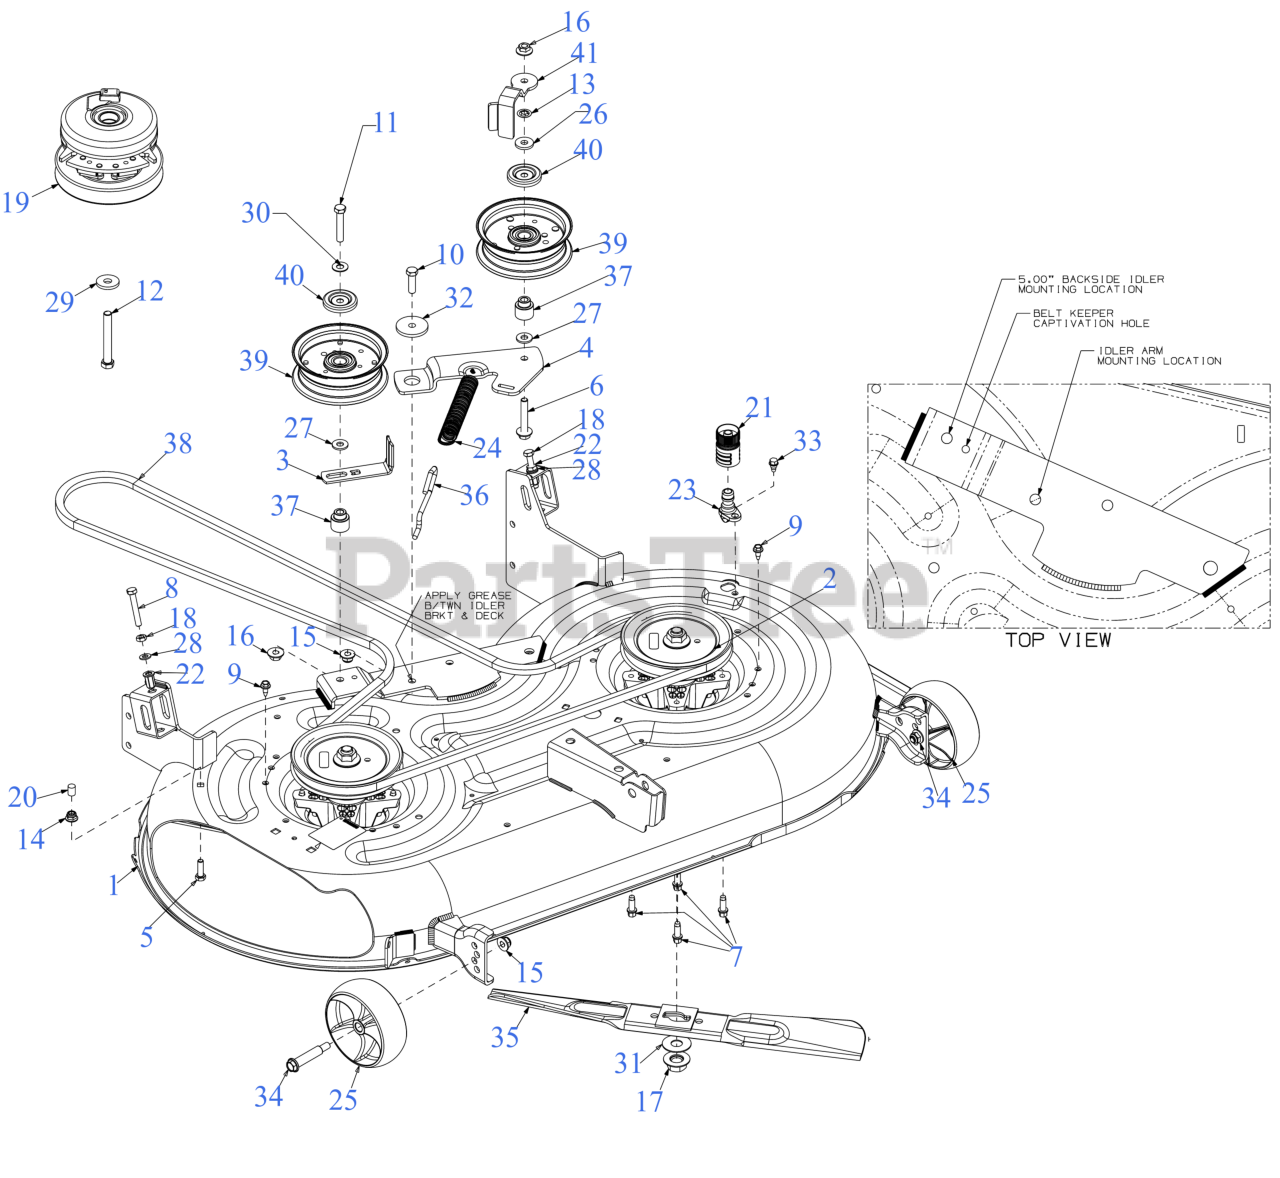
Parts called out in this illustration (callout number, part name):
1	42" DECK SHELL
2	SPINDLE ASSEMBLY (6.3 DIA)
4	42" IDLER PIVOT BRACKET
5	SCREW 5/16-18 x 1.0 GR5
6	SCREW 3/8-16 x 2.25 GR5
7	SCREW 5/16-18 x .875
8	SCREW-FULL THREAD 5/16-18 GR5
9	SCREW 1/4-20X.625
10	SCREW 3/8-16 x 1.25 GR5
11	SCREW 3/8-16 x 2.0 GR 8
12	SCREW 7/16-20 x 3.25 GR5
14	FLANGE LOCK NUT 5/16-18
16	FLANGE LOCK NUT
17	HEX FLANGE NUT 5/8-18 GR5
19	ELECTRIC PTO CLUTCH
21	WATER NOZZLE ADAPTER
22	NUT RIVET 5/16-18
23	DECK WASH NOZZLE
24	EXTENSION SPRING .94 x 6.75 RZT
25	DECK WHEEL (5.0 DIA x 1.875)
25	Cub Cadet 5" DECK WHEEL SET (06305A) (W/BOLT)
26	FLAT WASHER .385 x 1.00 x .135
27	FLAT WASHER .385X.870X.090
28	FLAT WASHER
29	FLAT WASHER .445 x 1.248 x .170
30	FLAT WASHER .401X.88
31	FLAT WASHER .635X1.585X.062 HDN
32	SHOULDER SPACER
33	SHOULDER SCREW 1/4-20 x .50
34	SHOULDER BOLT (.50 X 2.0 x 3/8 -16)
35	21.23" BLADE (2IN1) (S SHAPE CENTER HOLE)
35	21.23" XTREME BLADE (2IN1) (S SHAPE CENTER HOLE)
35	21.23" LOW LIFT BLADE (S SHAPE CENTER HOLE)
36	DECK SPRING HOOK
37	SHOULDER SPACER
38	V-BELT A SEC x 117.0
38	Cub Cadet 42" RZT DECK BELT
38	Genuine Factory Parts 42" DECK BELT (-06134)
39	IDLER PULLEY 4.50" DIA
40	IDLER PULLEY CAP
41	BELT KEEPER
